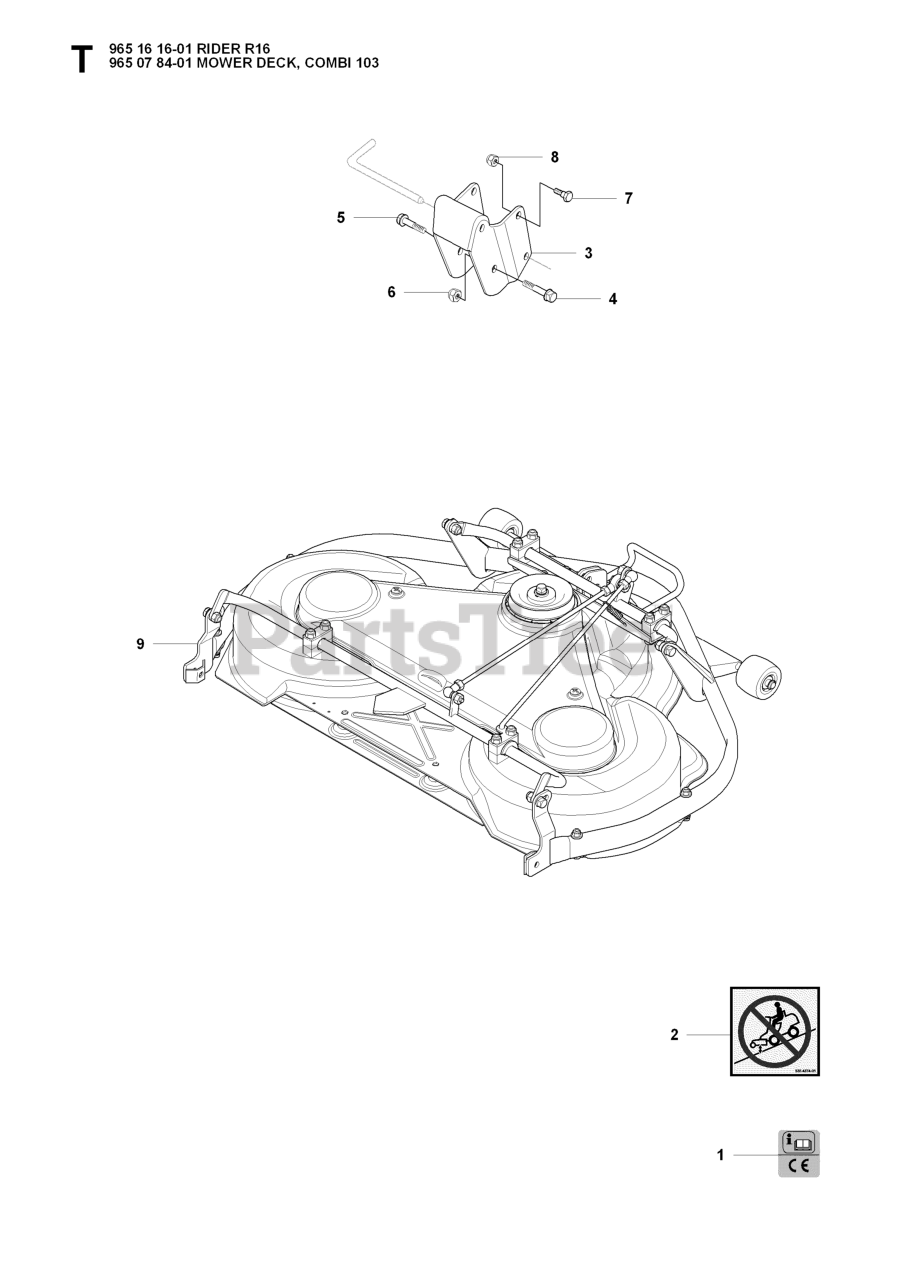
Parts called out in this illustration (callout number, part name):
5	Hex Head Capscrew, M12 X 1.75 X 30 DIN933ZP
8	LOCKNUT M8
9	DECK COMBI 103
